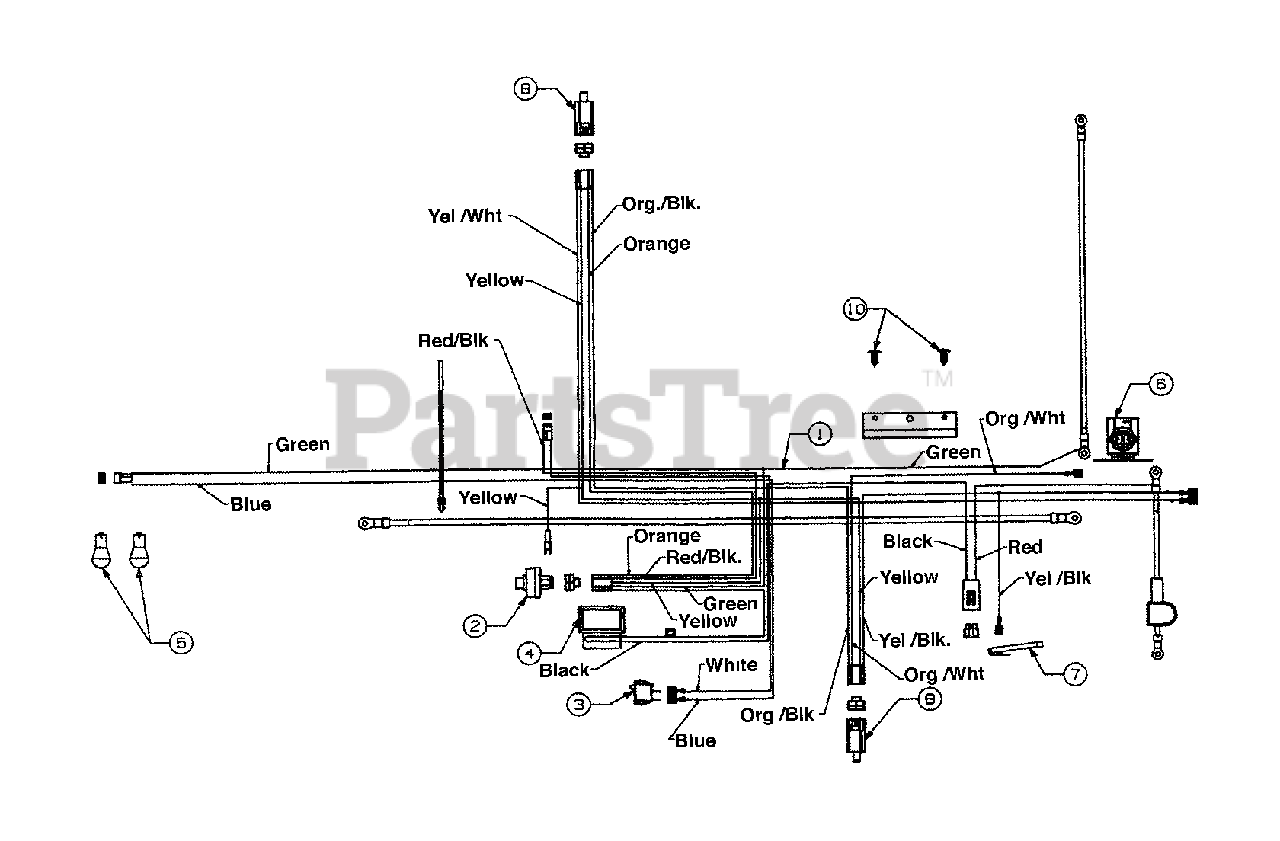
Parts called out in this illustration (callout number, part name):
1	Wire Harness w/Light Switch & Amp
2	Ignition Switch
3	Light Switch
4	Ammeter
5	Bulb (Headlight)
6	Solenoid
7	Safety Switch (Reverse)
8	Safety Switch
10	Ratchet
